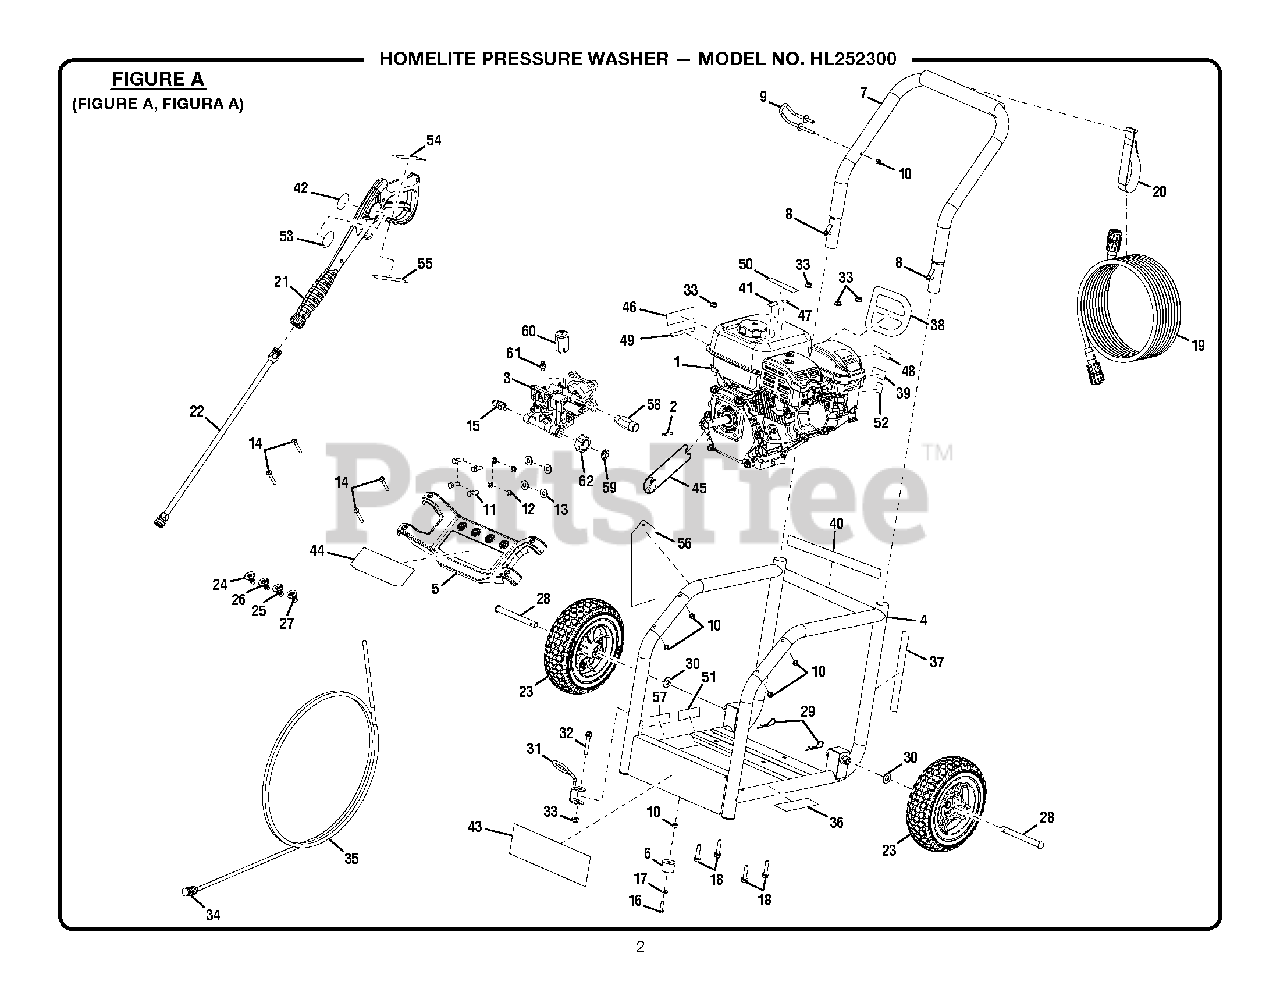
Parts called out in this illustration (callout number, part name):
2	Output Shaft Key (3/16 x 35 mm)
3	Pump
4	Main Frame
5	Nozzle Holder
6	Rubber Foot
7	Handle Assembly
8	Lock Button w/Spring Clip
9	Wand Holder (Upper)
10	Lock Nut (1/4-20)
11	Bolt (5/16-24 x 27 mm, Hex Hd.)
12	Lock Washer (5/16 in.)
13	Washer (5/16 in.)
14	Screw (1/4-20 x 2.0 in., Torx)
15	Thermal Release Valve
16	Bolt (1/4-20 x 1-1/4 in.)
17	Washer (1/4 in.)
18	Bolt (M8 x 40 mm, Hex Flange Hd.)
20	Hook and Loop Strap
21	Trigger Handle
22	Extension Wand
23	Wheel Assembly (10 in. x 3 in.)
24	Nozzle, 0deg
25	Nozzle 40deg
26	Nozzle 25deg
27	Soap Nozzle
29	Hitch Pin
30	Washer (1/2 in.)
31	Wand Holder (Lower)
32	Bolt (M8 x 50 mm, Flange Hd.)
33	Lock Nut (M8 x 1.25)
35	Chemical Siphon Tube
36	Pump Start Label
37	Engine Start Label
38	Recoil Label
39	Choke Label
40	Data Label
41	Hot Surface Label
42	Trigger Handle Logo Label
43	Homelite Label
44	Performance Label
45	Add Oil Label
46	Danger Label
47	E85 Label
48	Homelite Inquiries Label
49	Emc Compliance Label
50	No Oil To Gas Label
51	Combustion Label
52	Fuel Label
53	Trigger Handle Warning Label (English)
54	Warning Label (French and Spanish)
55	Wand Label (Max Rating)
56	Danger Hangtag
57	Lubricant Label
58	Outlet Tube
59	Filter Screen
61	Detergent Suction Kit
62	Inlet Tube
